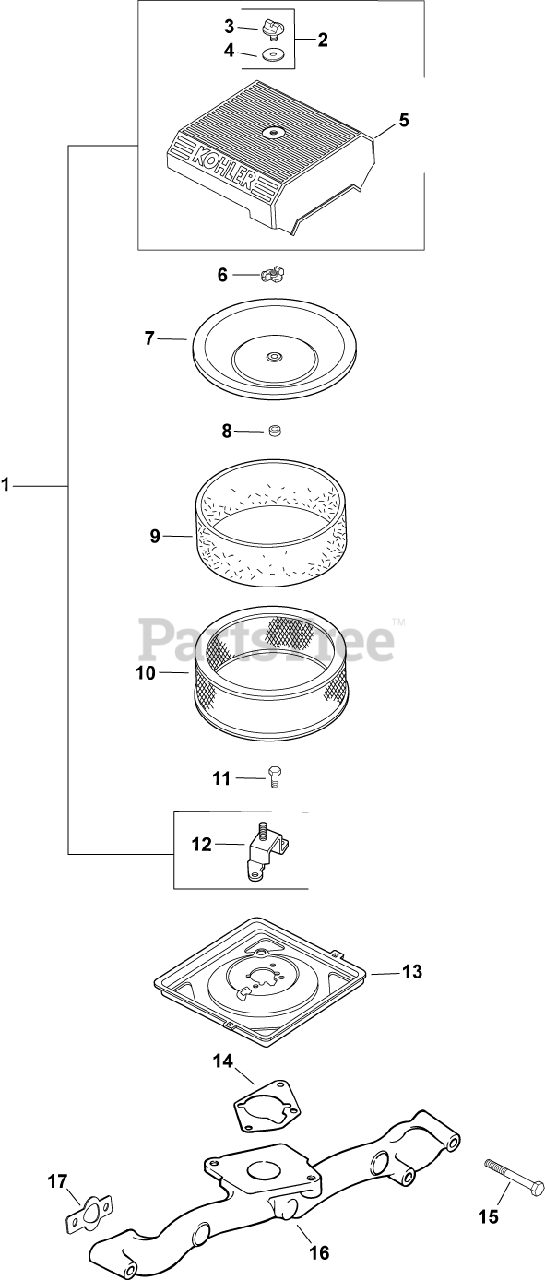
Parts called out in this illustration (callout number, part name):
1	KIT, AIR CLEANER COVER
2	KIT, KNOB W/SEAL
3	KNOB, COVER
5	COVER, AIR CLEANER
6	NUT, WING
7	COVER, INNER AIR CLEANER
8	SEAL, BREATHER
9	PRE-CLEANER (HIGH)
10	ELEMENT, AIR FILTER (HIGH) - Also available Retail Packaged 24 883 03-S1 Air Filter Kit
11	SCREW, CAPTIVE WSHR - DISC.
12	BRACKET, AIR CLEANER-USE 24 126 210-S
13	BASE, AIR CLEANER -USE 24 094 88-S
14	GASKET, AIR CLEANER BASE
15	SCREW, FLG M6X1.0X55
16	MANIFOLD, METAL INTAKE
17	GASKET, INTAKE MANIFOLD USE 24 041 79-S
